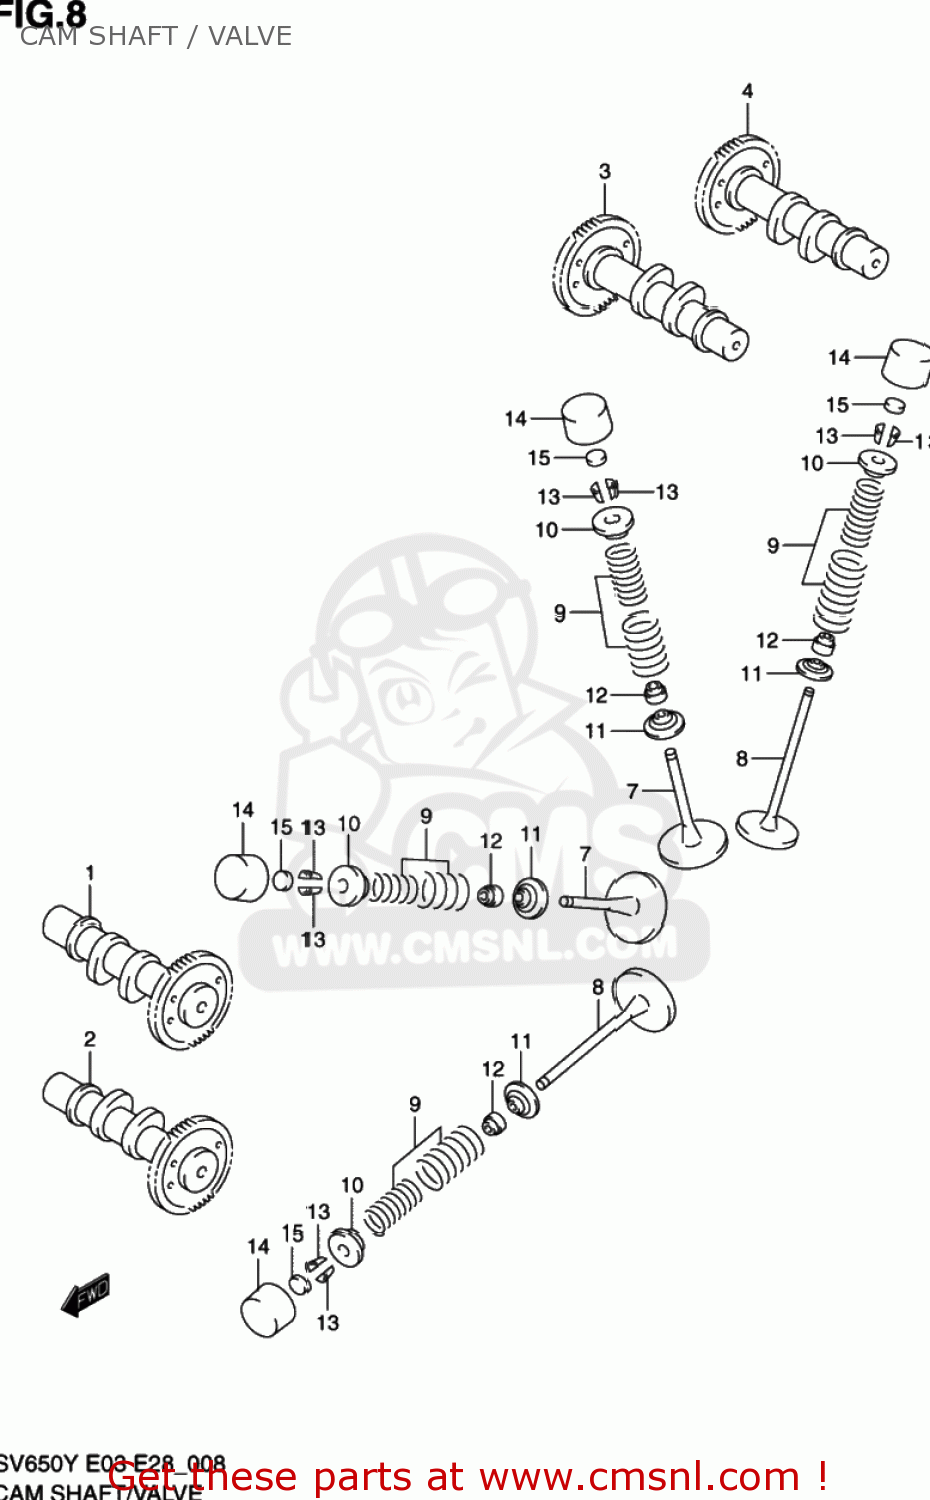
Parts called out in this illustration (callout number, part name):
1	CAMSHAFT,INTAKE FR
2	CAMSHAFT,EXHAUST FR
3	CAMSHAFT,INTAKE RR
4	CAMSHAFT,EXHAUST RR
5	SHIM SET,TAPPET
6	CASE,TAPPET SHIM
7	VALVE,INTAKE
8	VALVE,EXHAUST
9	SPRING SET,VALVE
10	RETAINER,VALVE SPRING
11	SEAT,VALVE SPRING
12	SEAL,OIL(4.5X10X8)
13	COTTER VALVE
14	TAPPET
15	SHIM,TAPPET
